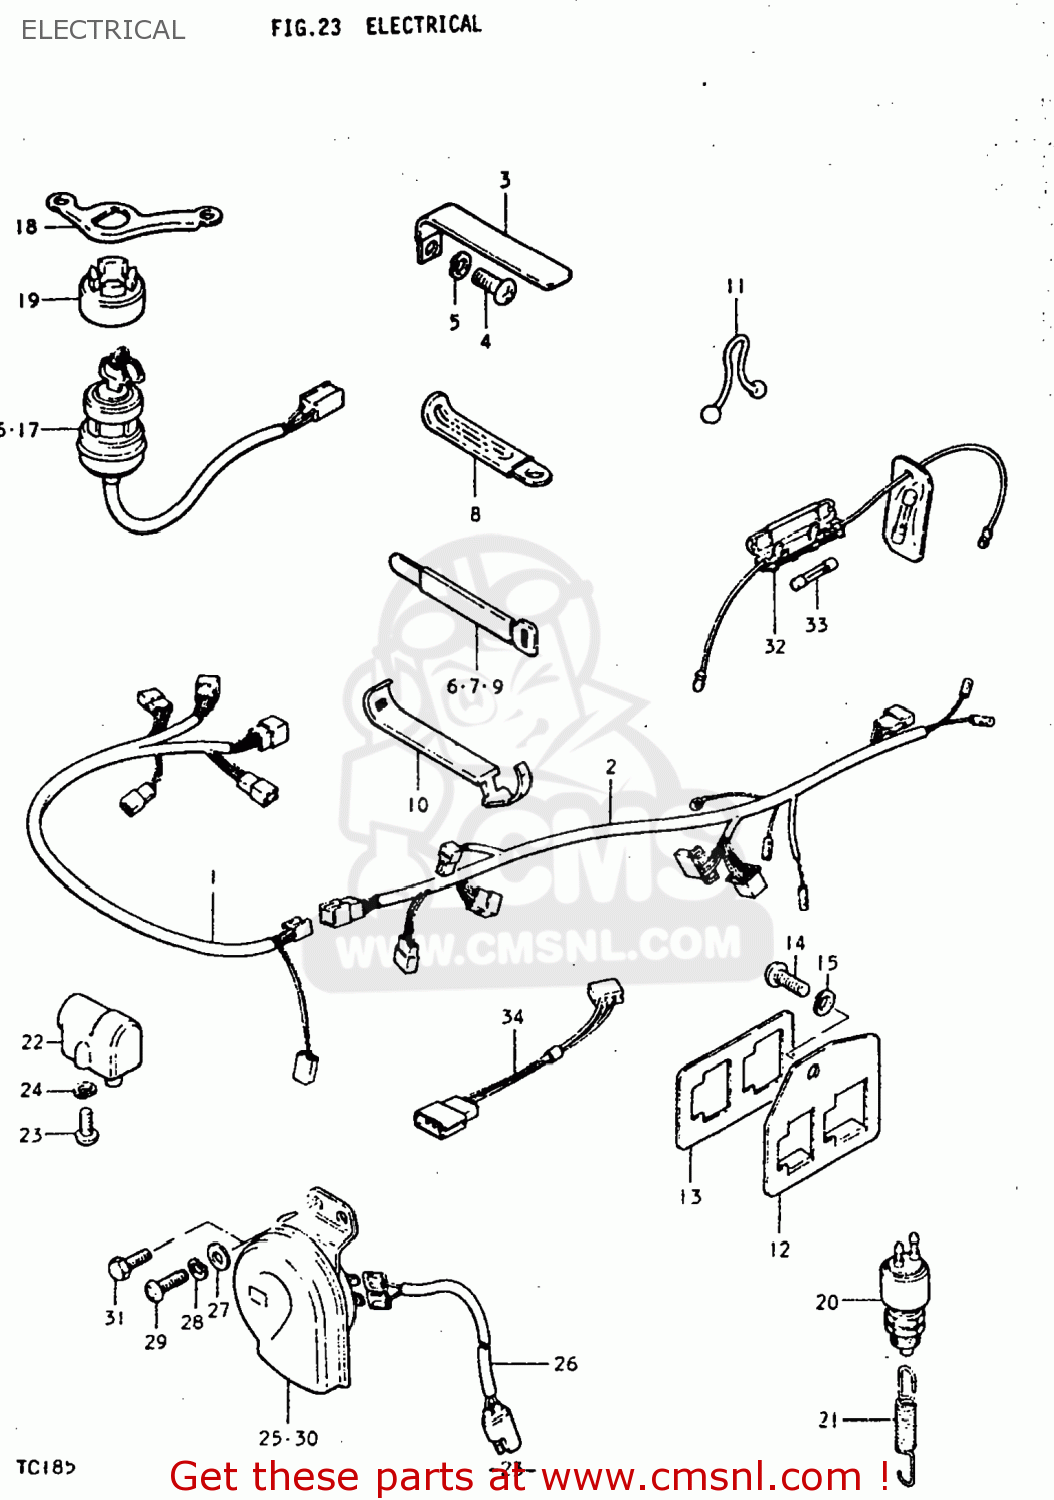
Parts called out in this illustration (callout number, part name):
1	HARNESS,WIRING
2	HARNESS,WIRING NO.2
3	CLAMP
4	SCREW 6X12
5	LOCK WASHER
6	CLAMP(L:250)
7	CLAMP
8	CLAMP
9	CLAMP
10	BAND
11	CLAMP
13	HOLDER,COUPLER
14	SCREW 6X12
15	LOCK WASHER
16	SWITCH ASSEMBLY,IGNITION
17	SWITCH ASSEMBLY,IGNITION
18	BRACKET,IGNITION SWITCH
19	IGN SWITCH COVE
20	SWITCH ASSY,BRAKE LAMP
21	SPRING
22	LOCK ASSY,STEERING
23	Screw
24	LOCK WASHER
25	HORN ASSEMBLY
26	WIRE,HORN LEAD
27	WASHER
28	LOCK WASHER
29	SCREW 6X12
30	HORN ASSEMBLY
31	BOLT
32	BOX ASSEMBLY,FUSE
33	FUSE(15A)
34	WIRE
